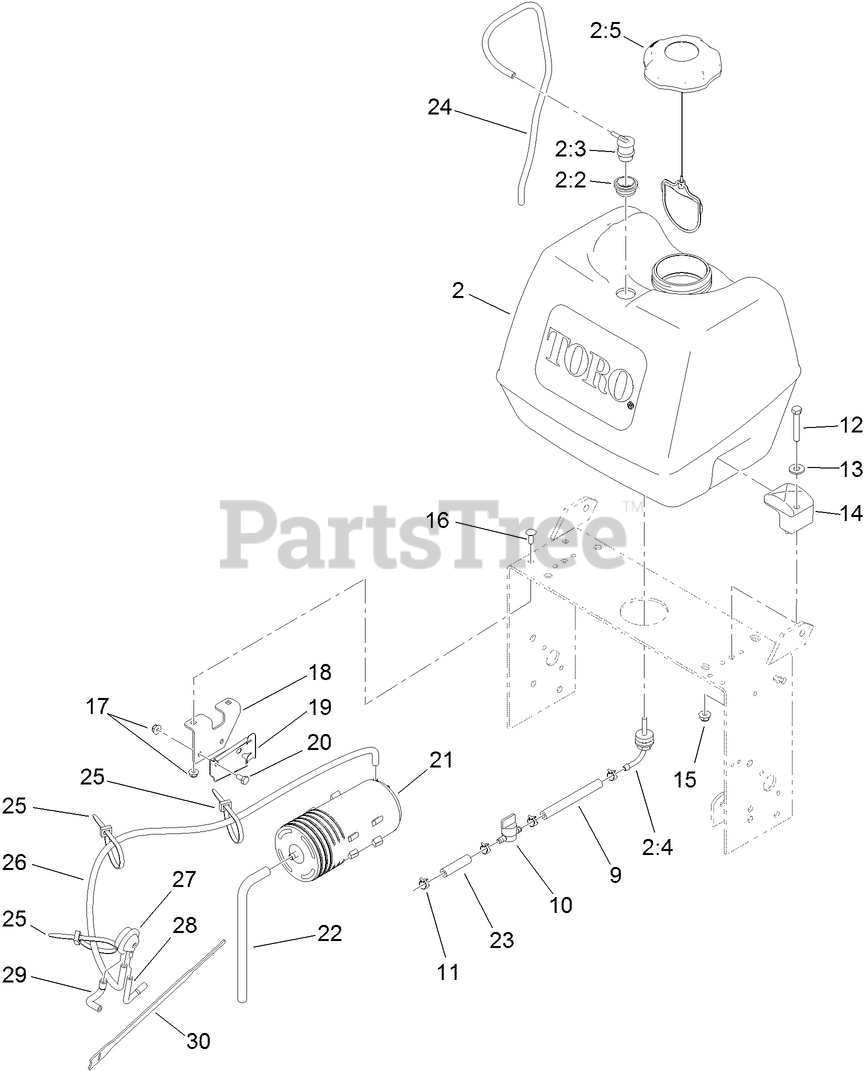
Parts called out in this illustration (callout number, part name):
2	FUEL TANK ASM
2:2	GROMMET
2:3	VALVE-ROLLOVER
2:4	FITTING-FUEL, BULKHEAD
2:5	CAP-FUEL, RATCHETING
9	HOSE-FUEL
10	VALVE-FUEL
11	CLAMP-HOSE
12	SCREW-HH
13	WASHER-FLAT
15	NUT-HF, NI
16	BOLT-CARR
17	NUT-HF
18	BRACKET-CANISTER, CARBON
19	BRACKET-CANISTER, CARBON
20	SCREW-HH
21	CANISTER-CARBON, 800CC
22	HOSE-VENT, CANISTER
23	HOSE-FUEL
24	HOSE-VENT
25	TIE-CABLE
26	HOSE-VENT, FORMED
27	VALVE-CONTROL, VACUUM
28	HOSE-VENT, FORMED
29	HOSE-VENT, FORMED
30	STRAP-VELCRO, CABLE TIE
